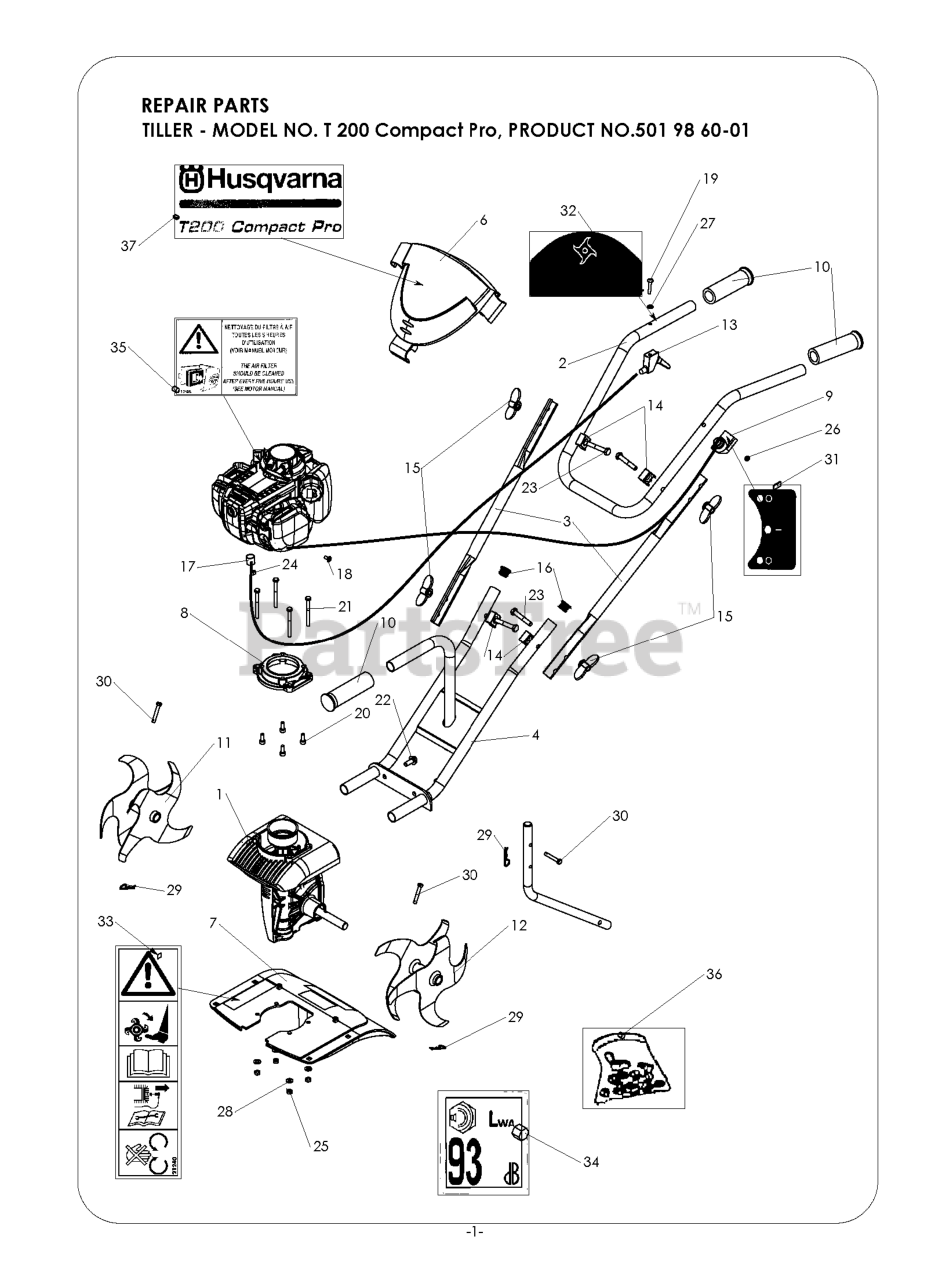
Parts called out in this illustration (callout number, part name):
1	TRANSMISSION
25	Blocking nut M 6 Z
29	COTTER PIN
